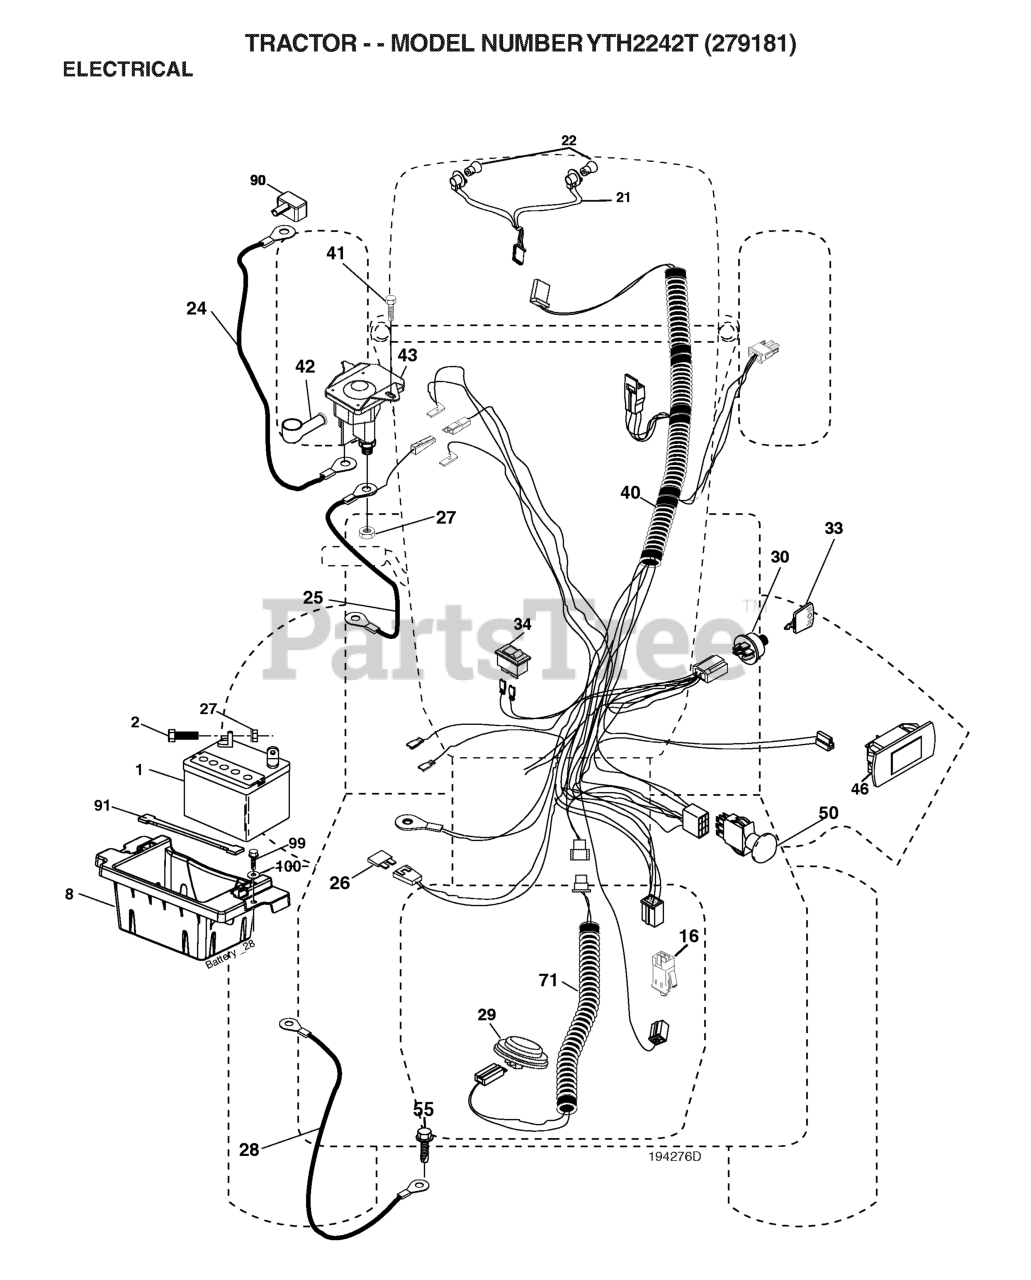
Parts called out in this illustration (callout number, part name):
1	BATTERY 12V .35 AMP
2	BOLT.HEX.1/4.X.3/4.DICHROMATE
8	BOX.BATTERY.MOUNT.FRONT.LT
16	SWITCH INTERLOOK PUSH-IN
21	HARNESS ASSY LIGHT
24	CABLE.BATT.POS.WIRE.TG.DA SOL
25	CABLE.START.RED.17.5".
26	FUSE 20AMP
27	NUT
28	CABLE GROUND 6 GA 21" 90T BLK
29	SWITCH.SEAT.DELTA.OPC.
30	SWITCH.IGN.DELTA.W.LGH.ROS
33	KEY MLD GEN DELTA
40	HARNESS.IGN.DASH.HUQ/P
41	SCREW
42	TERMINAL COVER
43	SOLENOID.W/BRASS.PLUNGER
46	GAUGE.SERVICEMINDER.HR
50	RP.PTO.SWITCH.8 TERMINAL.BLACK
55	SCREW.THDROL.5/16-18X3/4.TTY
71	HARNESS-CHASSIS SUB
90	COVER.TERMINAL.BATTERY
91	STRAP.BATTERY.MOUNT.FRONT(2 2)
99	SCREW HEXWSHR 1/4-20X3/4
